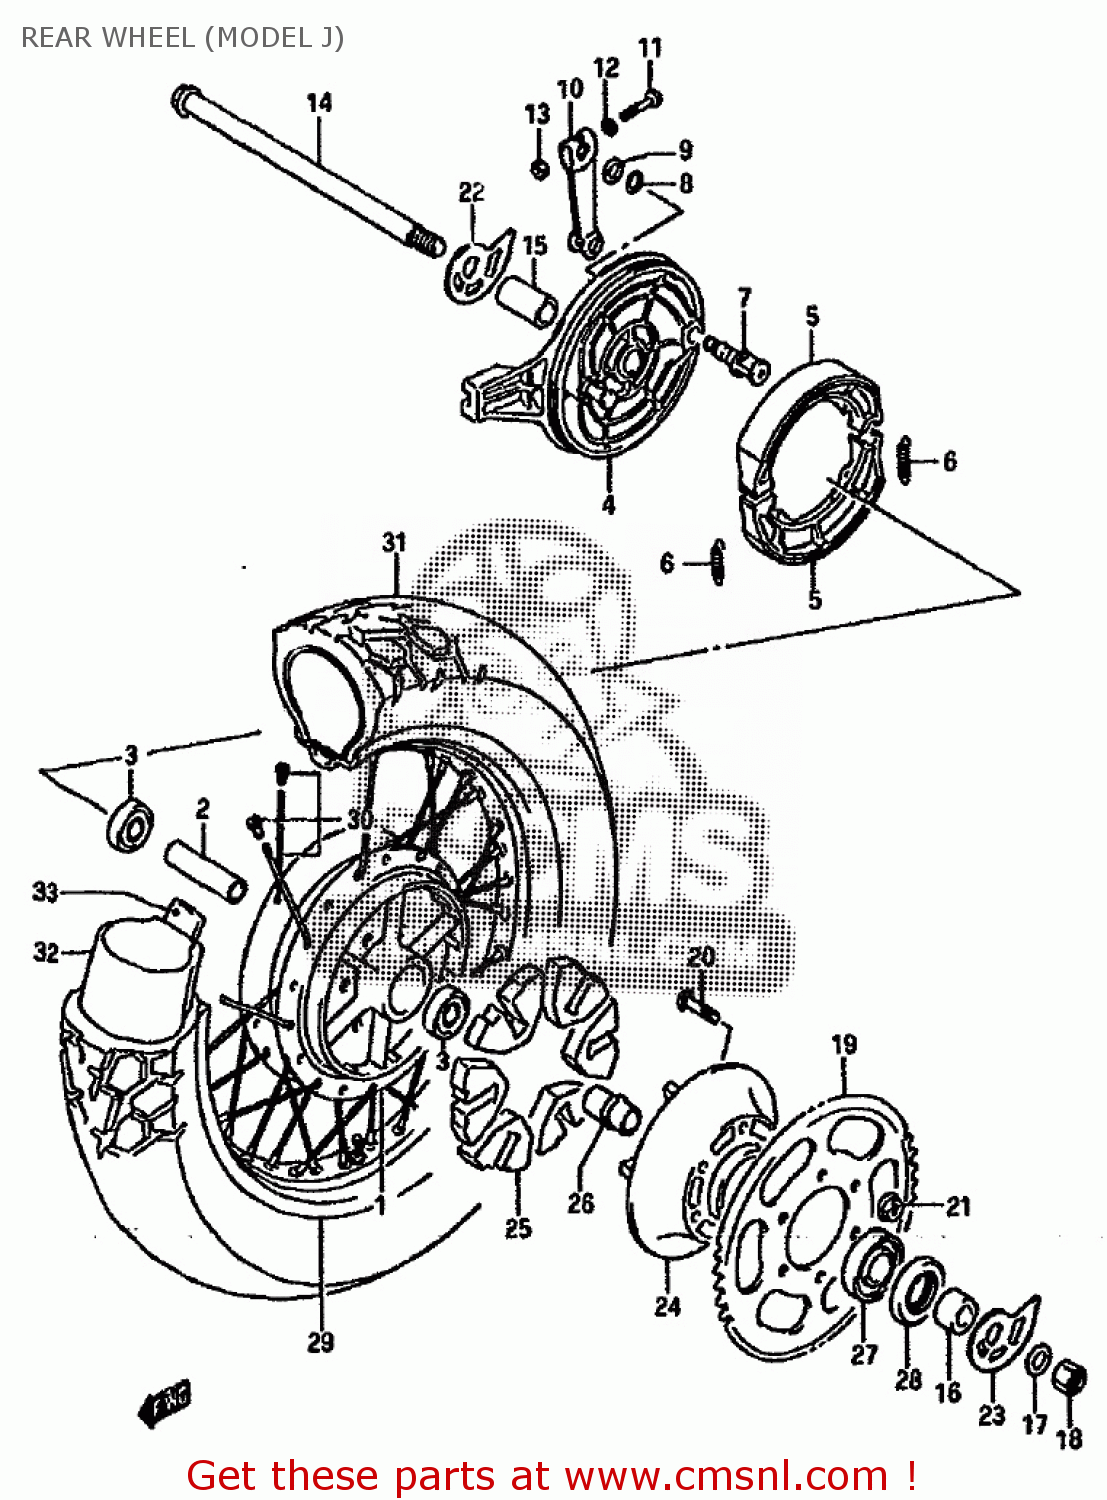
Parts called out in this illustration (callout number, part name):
1	HUB,REAR WHEEL
2	SPACER(17.5X25X70)
3	BEARING
4	PANEL,REAR BRAKE
5	SHOE,BRAKE
6	SPRING,BRAKE SHOE
7	CAM,FRONT BRAKE
8	O-RING,BOSS
9	WASHER (15X24X1.6)
10	LEVER,REAR BRAKE CAM
11	BOLT(6X35)
12	WASHER,LOCK
13	NUT
14	AXLE,RR
15	SPACER,RH
16	SPACER(17X33X22.4)
17	WASHER (17X30X3.2)
18	NUT
19	SPROCKET,RR(48T)
20	BOLT(10X37.5)
21	NUT
22	ADJUSTER,CHAIN,RH
23	ADJUSTER,CHAIN,LH
24	DRUM
25	ABSORBER,RR HUB SHOCK
26	RETAINER,RR SPROCKET DRUM
27	BEARING(25X62X17)
28	SEAL,OIL(33X62X7)
29	RIM,RR WHEEL(17XMT2.50)
30	SPOKE SET
31	TIRE
32	TUBE ASSEMBLY,WHEEL,INNER
33	PROTECTOR,INNER TUBE
